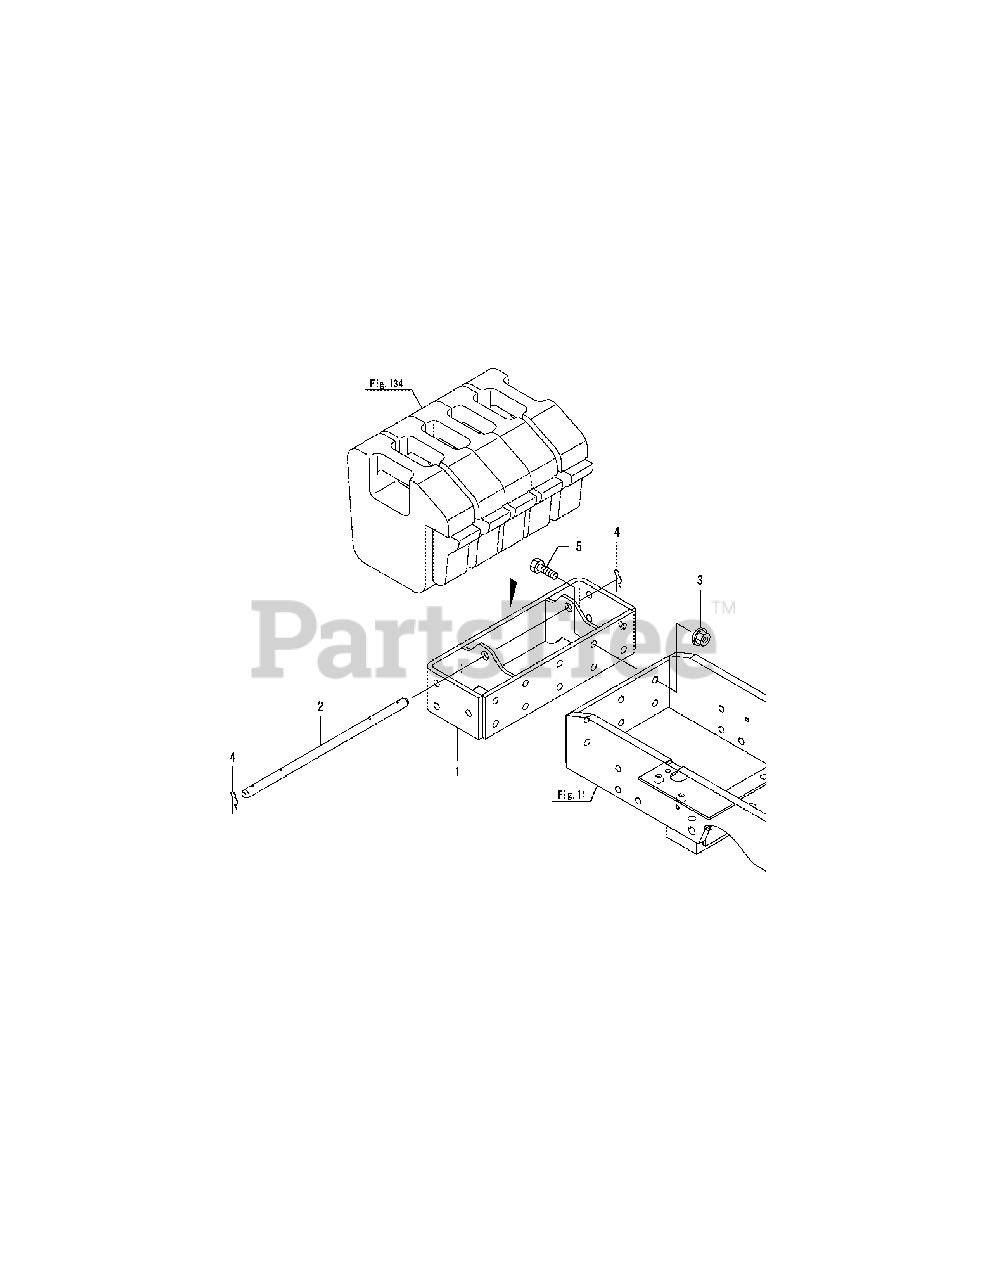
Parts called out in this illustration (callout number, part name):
2	LOCK PIN, WEIGHT
3	NUT W/WASHER 12
5	BOLT M12X 35 PLATED
